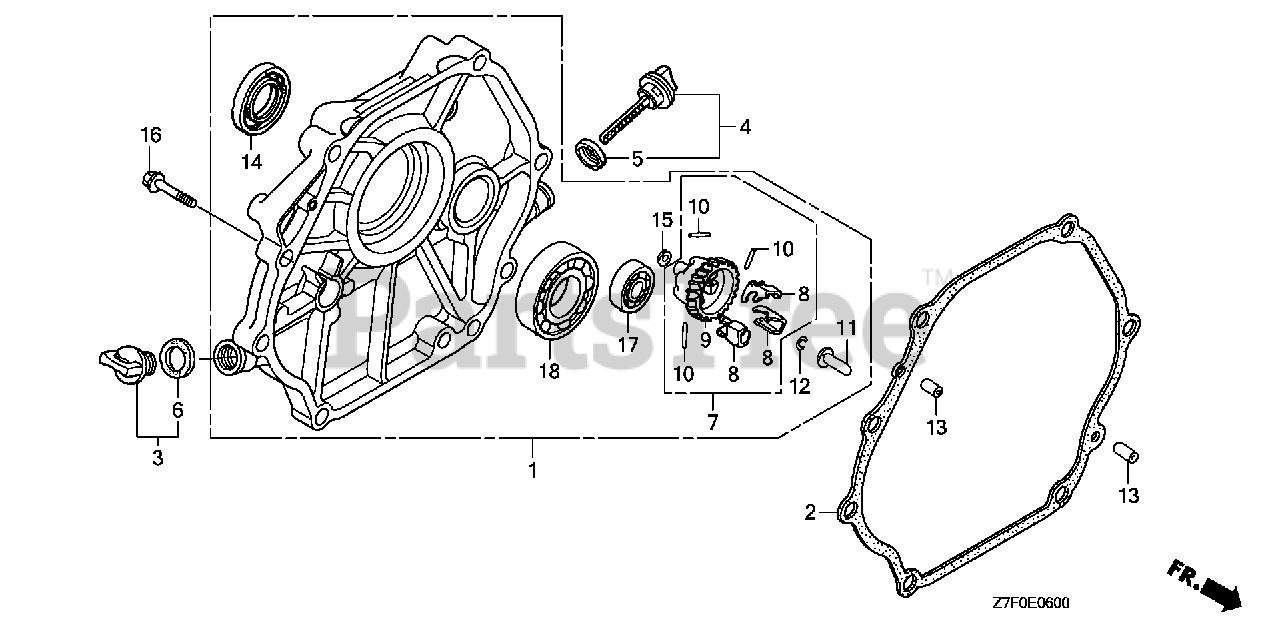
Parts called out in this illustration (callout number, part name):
1	COVER ASSY., CRANKCASE
2	GASKET, CASE COVER
3	CAP ASSY., OIL FILLER
4	CAP ASSY., OIL FILLER
5	GASKET, OIL FILLER CAP
6	GASKET, OIL FILLER CAP
7	GOVERNOR ASSY.
8	WEIGHT, GOVERNOR
9	HOLDER, GOVERNOR WEIGHT
10	PIN, GOVERNOR WEIGHT
11	SLIDER, GOVERNOR
12	CLIP, GOVERNOR HOLDER
13	PIN, DOWEL (8X12)
14	OIL SEAL (35X52X8)
15	WASHER, PLAIN (6MM)
16	BOLT, FLANGE (8X40)
17	BEARING, RADIAL BALL (6202)
18	BEARING, RADIAL BALL (6207)
